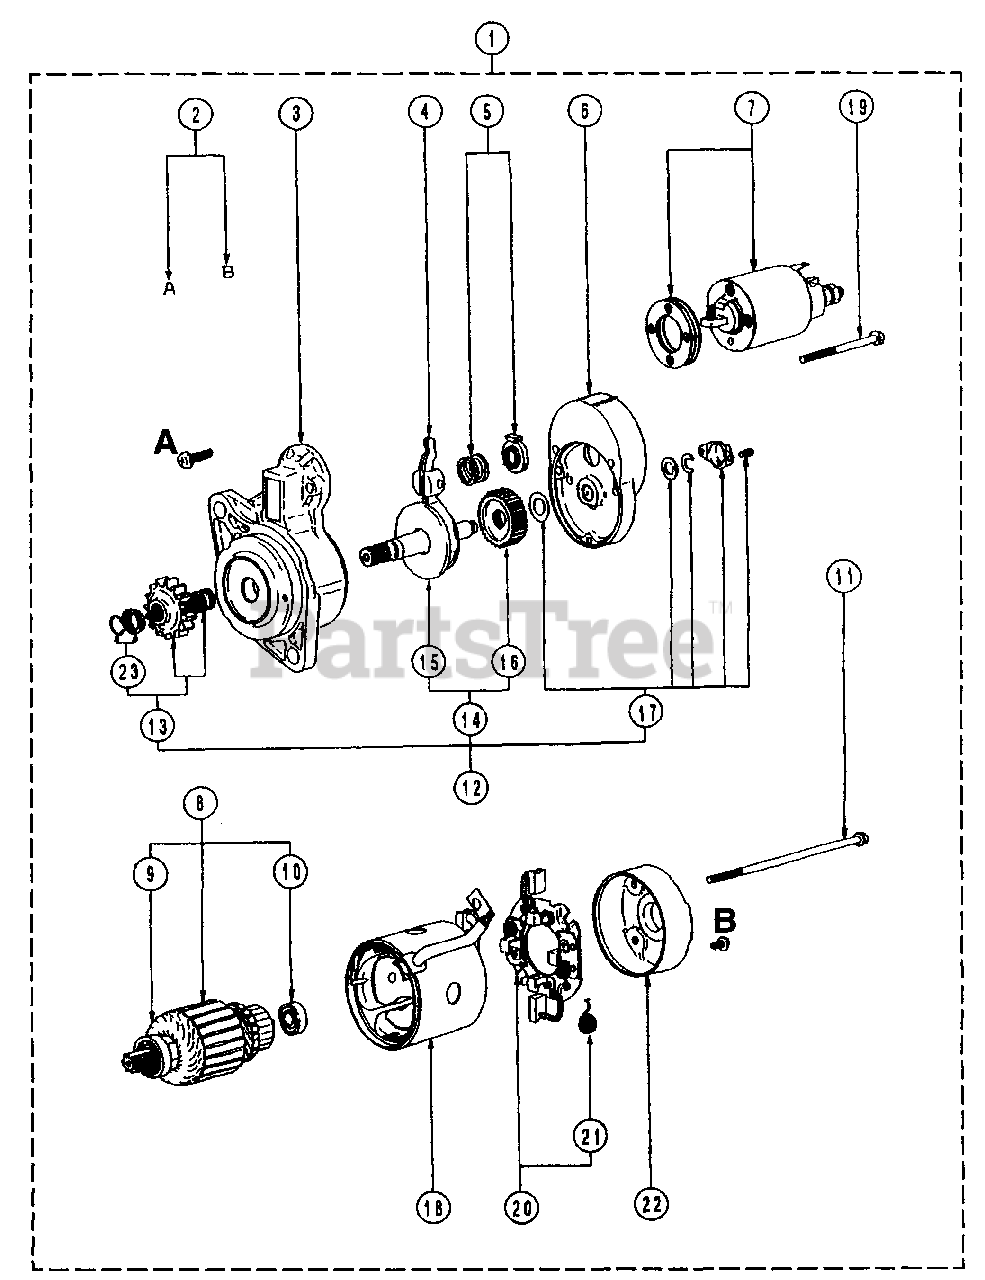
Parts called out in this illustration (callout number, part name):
1	Starter Ass'y
3	Bracket Ass'y, Front
6	Bracket Ass'y, Center
9	Bearing, Front
10	Bearing, Rear
12	Shaft Ass'y, Clutch
15	Shaft Ass'y, Pinion
20	Holder Ass'y, Brush
21	Spring, Brush
22	Bracket Ass'y, Rear
